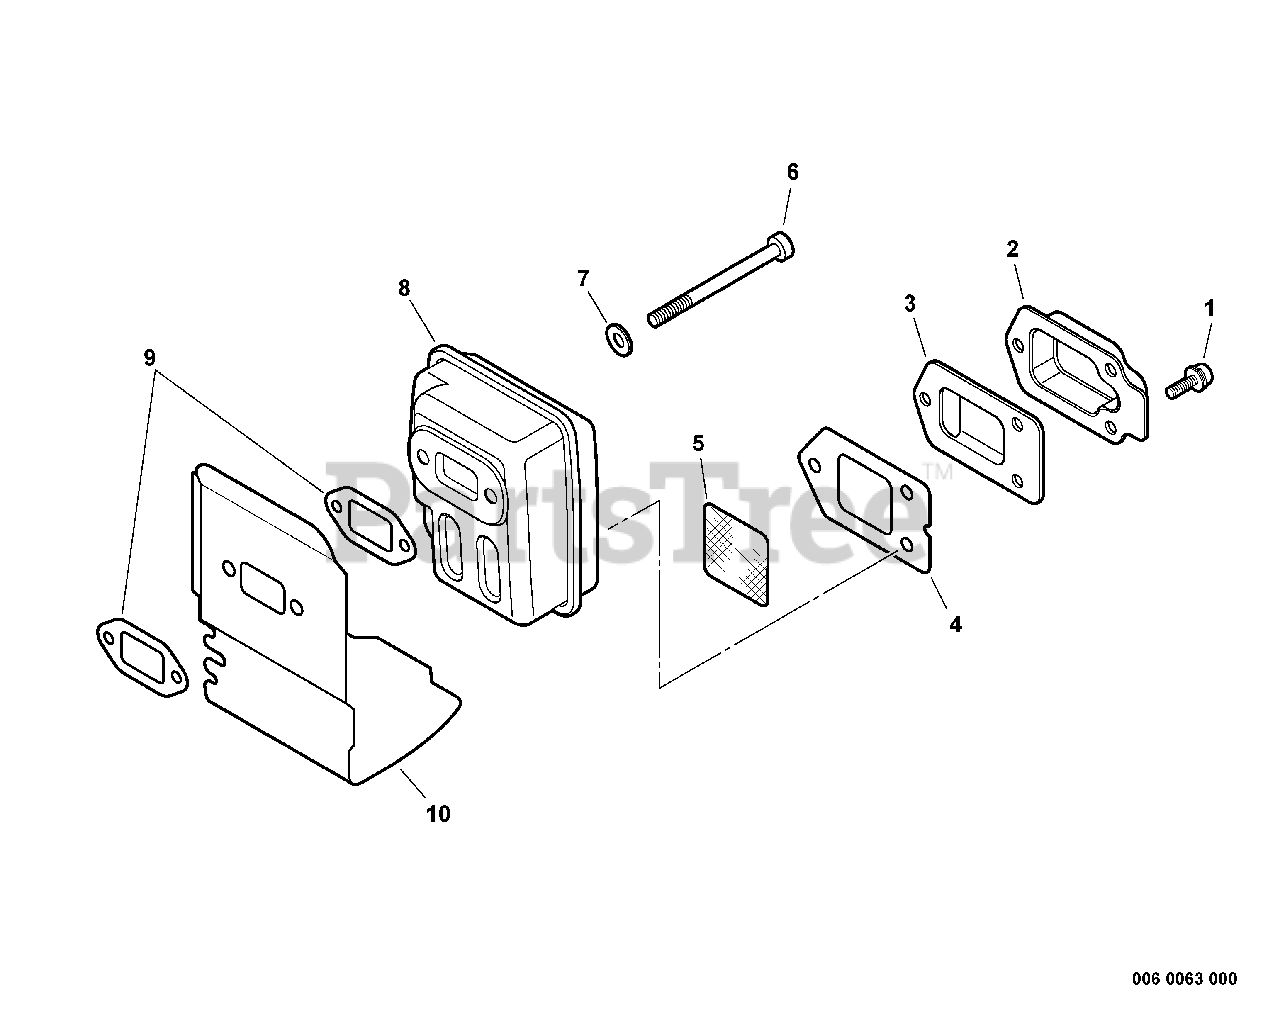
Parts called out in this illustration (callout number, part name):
1	SCREW - 4X10
2	GUIDE, EXHAUST - OUTER
3	GASKET, EXHAUST - INNER
4	GASKET, EXHAUST
5	SCREEN, SPARK ARRESTOR
6	SCREW - 5X55
7	WASHER - 5
9	GASKET, EXHAUST
10	SHIELD, EXHAUST
